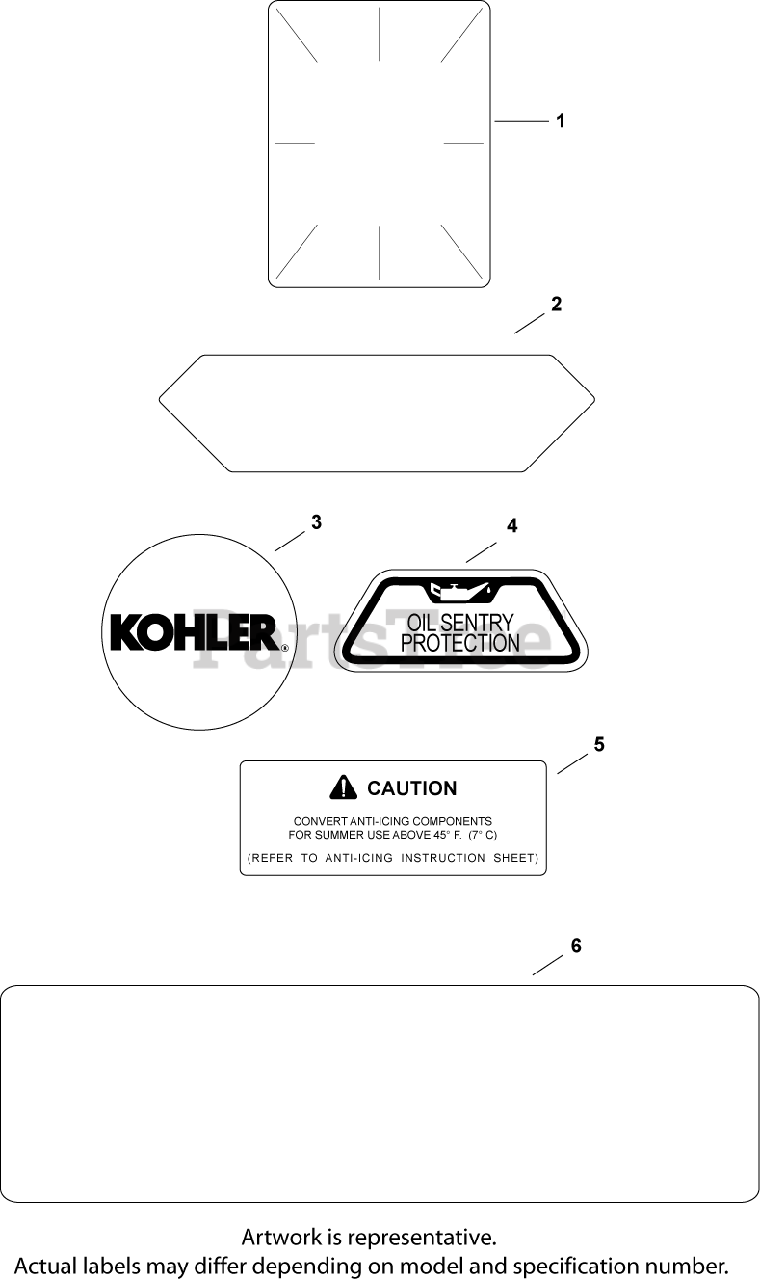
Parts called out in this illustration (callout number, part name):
1	DECAL, CLEAR LAMINATE USE 25 113 70-S
2	DECAL, AIR FILTER COVER
3	LABEL, (ROUND KOHLER GOLD)-USE 24 113 18
4	DECAL, OIL SENTRY - (#DSC)
5	DECAL, ANTI-ICING
6	DECAL, 27 HP
